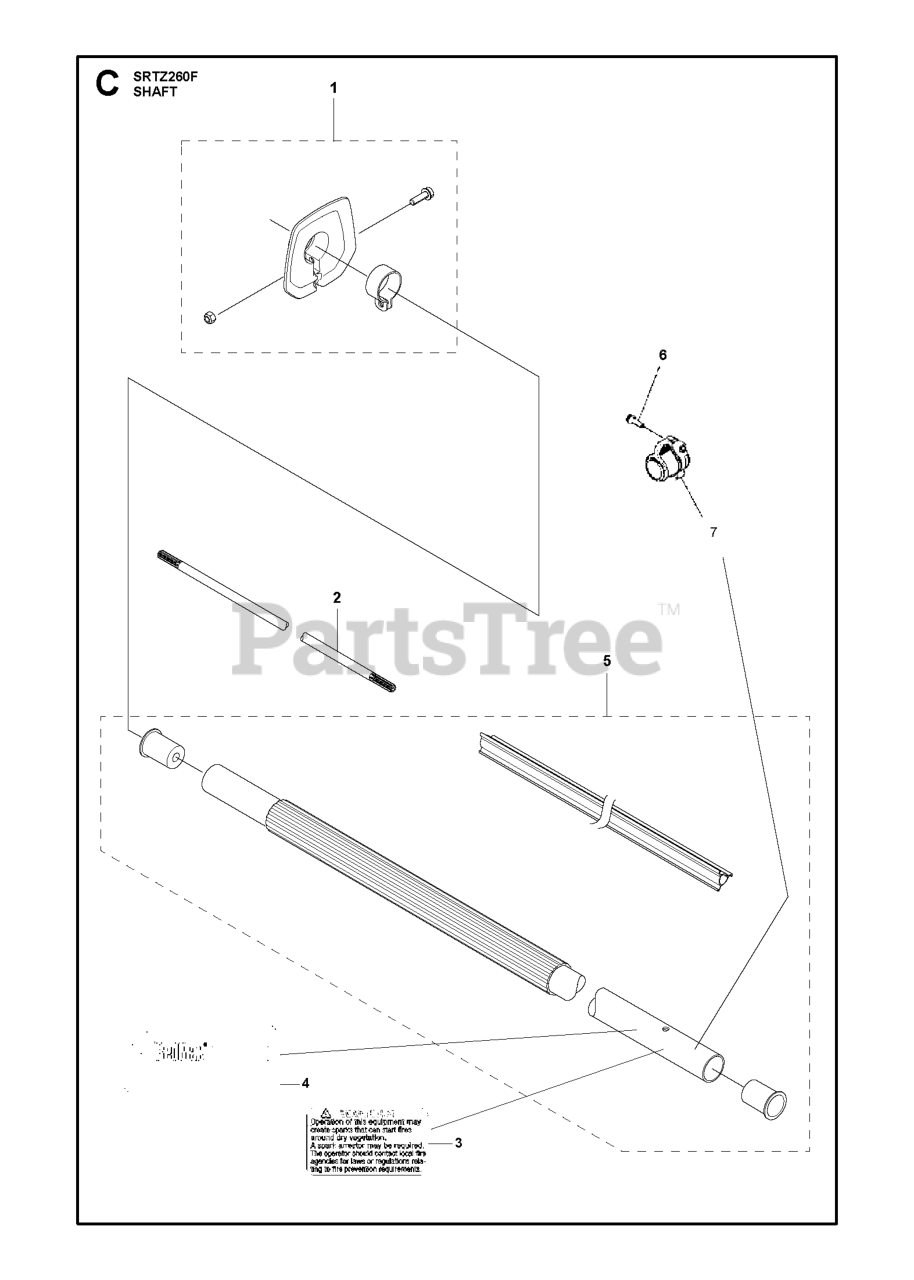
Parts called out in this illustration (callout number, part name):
1	HAND GUARD ASSY BLACK
2	DRIVESHAFT 525HF3S
3	DECAL SPARK ARRESTOR WARNING
5	TUBE ASSY WITH GRIP
7	HANGER COMP
